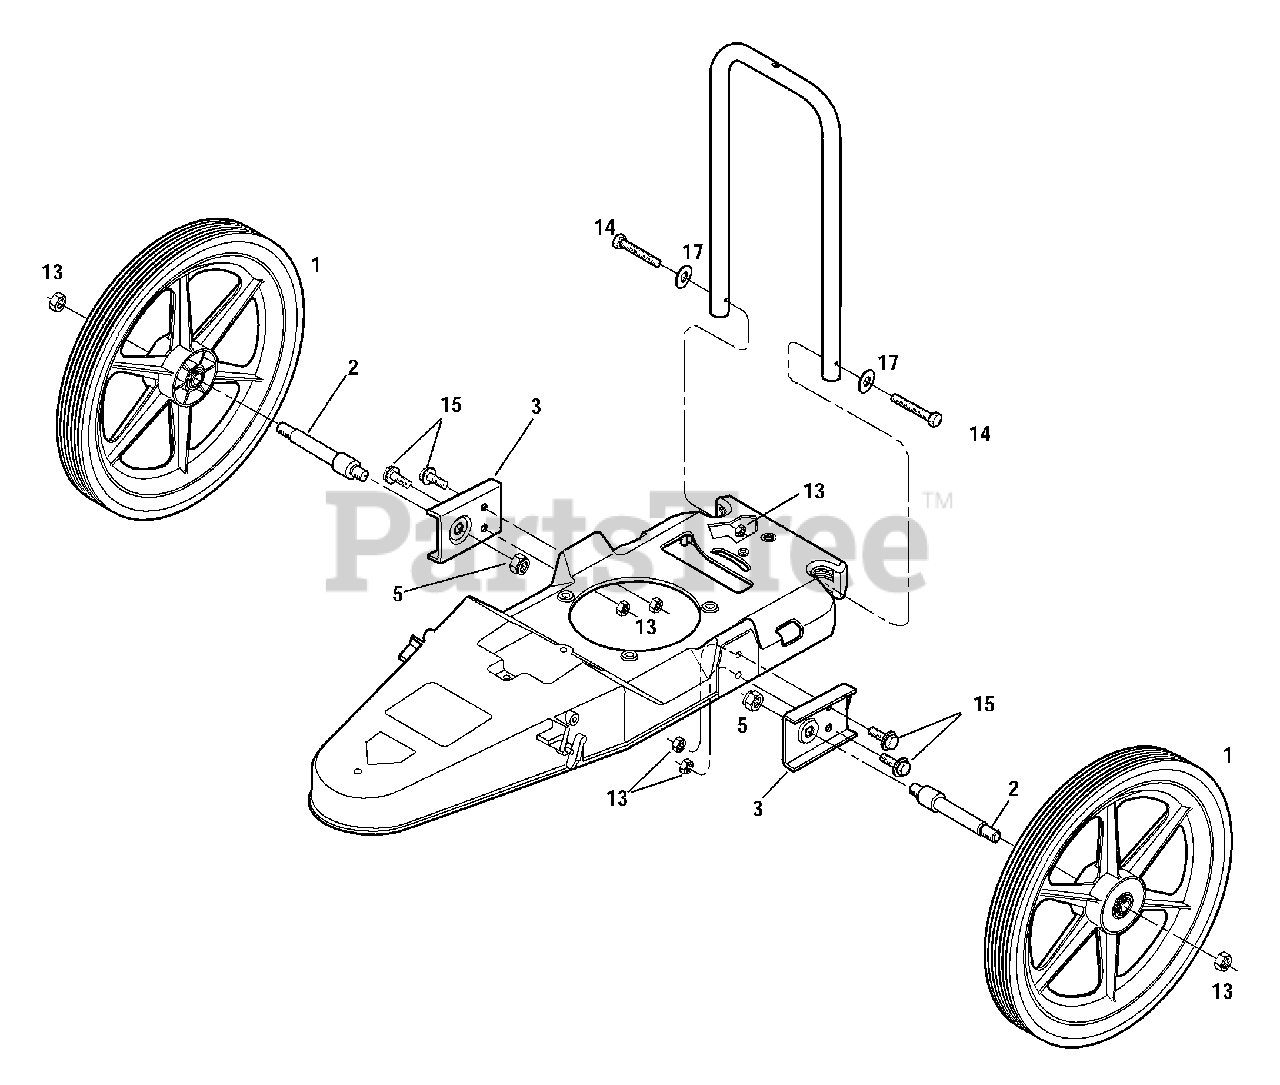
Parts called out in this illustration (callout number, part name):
1	Wheel - 6 spoke
2	Wheel Stud
3	Wheel Mounting Bracket
5	Top Lock Nut, 3/8-16
13	Hex Lock Nut, 5/16-18
14	Hex Head Bolt, 5/16-18 x 2
15	Hex Flange Screw, 5/16-18 x 1
17	Washer, 5/16 ID
